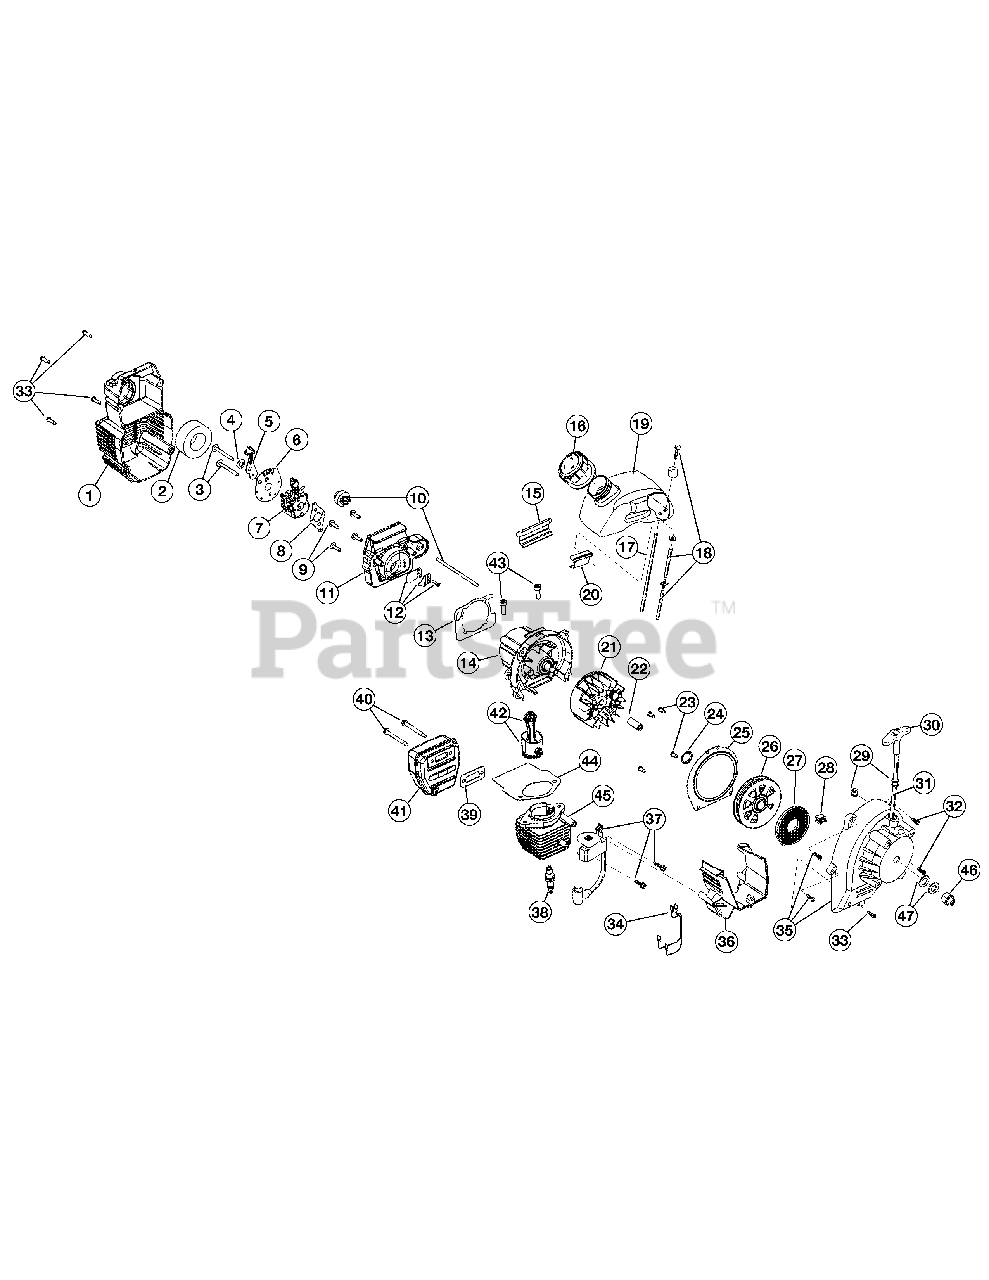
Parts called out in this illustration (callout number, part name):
1	Air Cleaner Cover Assembly
2	Air Cleaner Filter
3	Carburetor Mounting Screws
4	Wavey Washer
5	Choke Lever Assembly
6	Choke Lever & Plate
7	Carburetor Assembly
8	Carburetor Gasket
9	Carb Mount Screw
10	Primer & Hose Assembly
11	Carburetor Mount Assembly
12	Reed Assembly
13	Carburetor Mount Gasket
14	Crankcase Service Assembly
15	Rear Mounting Pad
16	Fuel Cap Assembly
17	Fuel Return Line
18	Fuel Line Assembly
19	Fuel Tank Assembly
20	Front Mounting Pad
21	Flywheel Assembly
22	Spacer
23	Plate Screw
25	Pressure Plate
26	Recoil Pulley Assembly
27	Recoil Spring
28	Eyelet Retainer
30	Pull Handle
32	Housing Screw
33	Cover Screw
35	Starter Housing Assembly (includes 23-33)
36	Shroud Extension and Stand (includes 33)
37	Module Assembly
39	Exhaust Gasket
40	Muffler Mounting Bolt Assembly
41	Muffler Assembly
42	Piston & Rod Assembly
43	Cylinder Bolt
44	Cylinder Gasket
45	Cylinder Assembly
46	Crankshaft Extension
47	Washer
